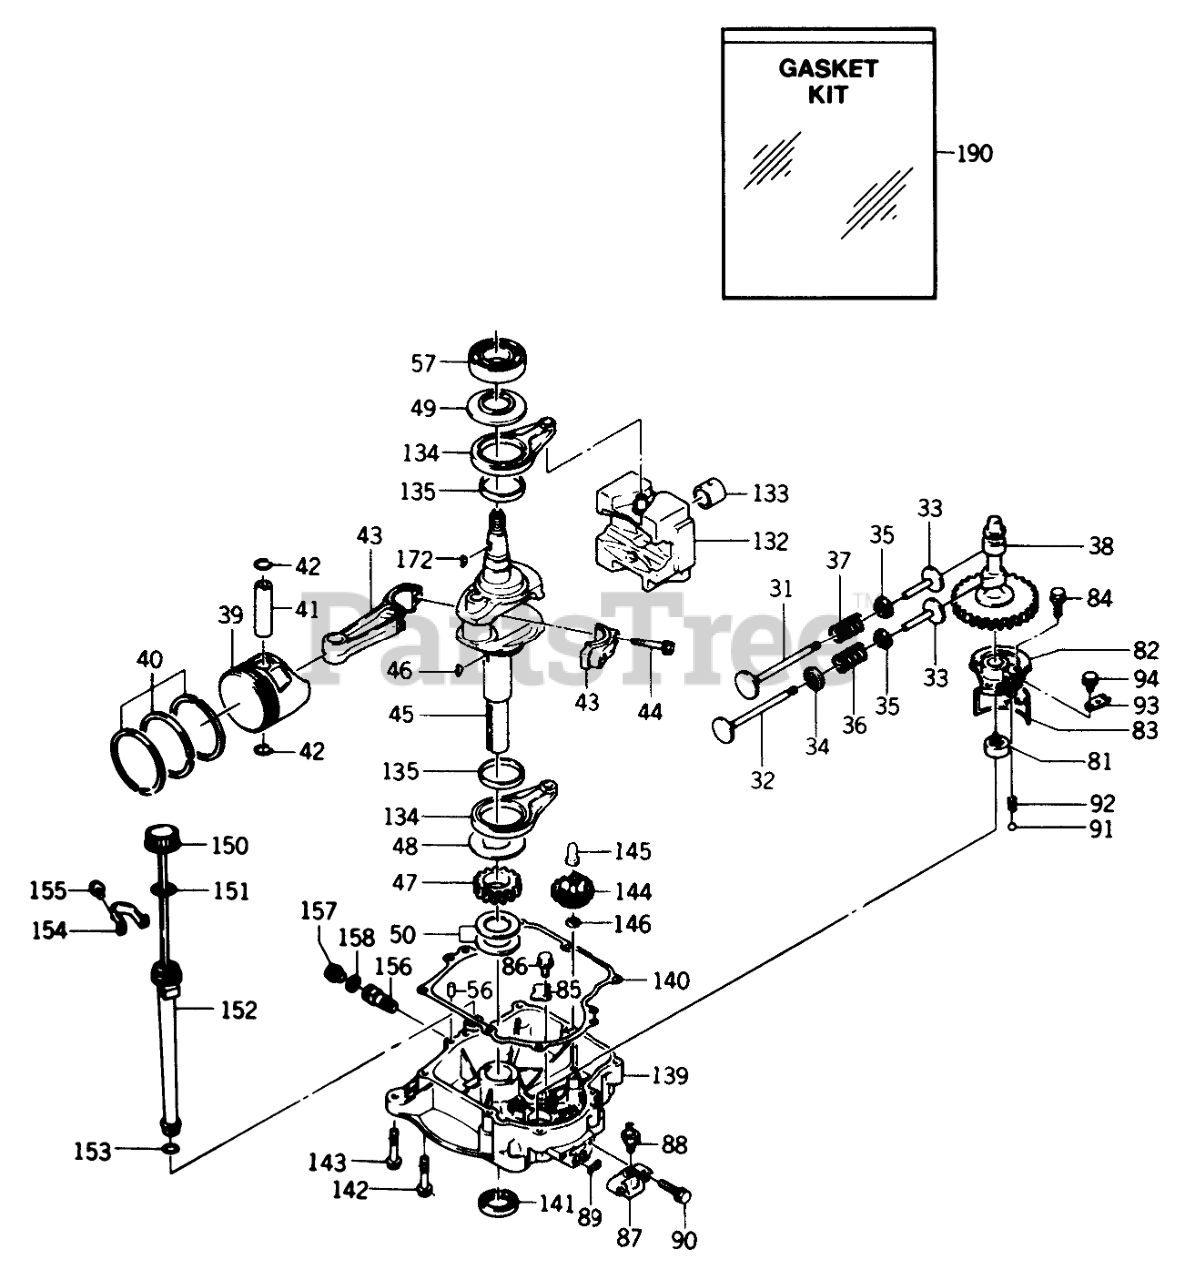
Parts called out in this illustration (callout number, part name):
31	VALVE-INTAKE
32	VALVE-EXHAUST
33	TAPPET-VALVE
34	ROTATOR-VALVE
35	RETAINER-VALVE
36	SPRING-VALVE
37	SPRING-VALVE
38	SHAFT-CAM
39	PISTON-(STD)
39	PISTON-.010 OVER
39	PISTON-.020 OVER
39	PISTON-.030 OVER
40	RING (STD)
40	RING (.010 OVER)
40	RING (.020 OVER)
40	RING (.030 OVER)
41	PIN-PISTON
42	RING-SNAP
43	Assy. Rod, Connecting Std. (Incl. Ref. #44)
43	Assy. Rod, Connecting .025mm Undersize (Incl. Ref.#44)
44	BOLT-CON ROD
45	CRANKSHAFT
47	GEAR-HELICAL
48	SPACER
49	SPACER
50	SHIM-T=1.18
50	SHIM-T=1.25
50	SHIM-T=1.32
50	SHIM-T=1.39
50	SHIM-T=1.46
50	SHIM-T=1.53
50	SHIM-T=1.60
50	SHIM-T=1.67
50	SHIM-T=1.74
57	BEARING-BALL #6207
81	PUMP OIL
82	COVER-PUMP
83	FILTER-INTERNAL OIL
84	BOLT, FLANGED 8X25
85	PLATE
86	Bolt
87	COVER
88	SWITCH-OIL PRESSURE
89	RING O
90	BOLT-FLANGED (8X30)
91	BALL-STEEL 5/16
92	SPRING
93	PLATE
94	BOLT-FLANGED
132	Weight-Complete (Incl. Ref. #133)
133	BEARING-PLAIN
134	Assembly-Rod (Incl. Ref. #135)
135	BEARING PLAIN
139	COVER-CRANKCASE
140	GASKET
141	SEAL OIL
142	BOLT-FLANGED
143	BOLT, FLANGED 8X25
144	GOVERNON
145	SLEEVE-GOVERNOR
146	WASHER
150	GAUGE-OIL
151	GASKET
152	FILLER
153	O-RING
154	CLAMP
155	Bolt
156	JOINT
157	PLUG DRAIN
158	GASKET
172	KEY-WOODRUFF
190	GASKET SET-OVERHAUL
191	Filter-Oil
193	BRACKET
194	O-Ring
195	GASKET
197	BOLT-FLANGED
198	RING O
